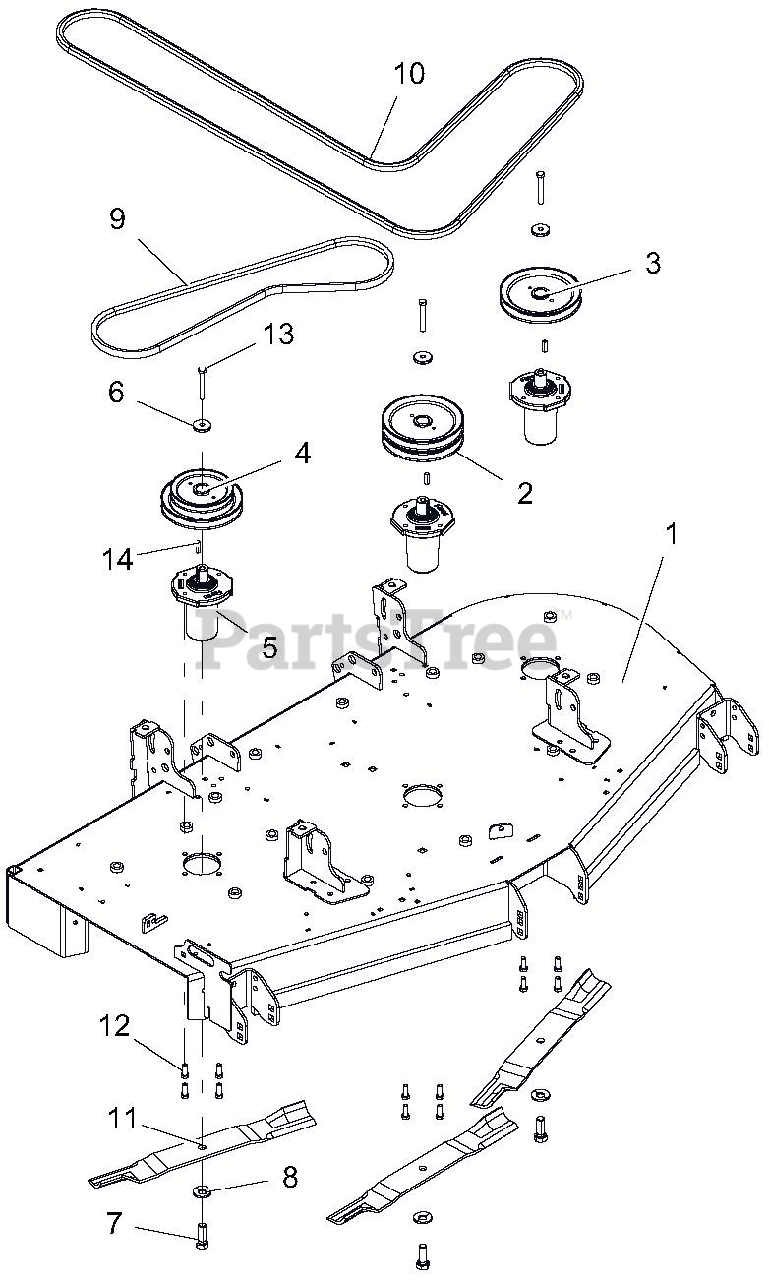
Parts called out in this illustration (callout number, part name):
1	WLDMT, 60" PT100 SIDE DISCH DECK
2	PULLEY, DOUBLE 1"ID X 6.75"OD-BLACK
3	PULLEY, V-1" ID X 6.75" OD-BLACK
4	PULLEY, DOUBLE -1" ID X 6.75" & 5.25" OD
5	SERVICE, ASM SPINDLE- DUCTILE
6	RETAINER, SHEAVE SPINDLE
7	BLT, HEX .62-18X1.75 GR8 YWZC
8	WSHR, BLVL .63X1.625X.14
9	BELT, B 63.00 RAW COGGED
10	BELT, BB 118.00 WRAPPED HEX
11	BLADE, MOWER 60"
12	BLT-HEX .38-16X1.00 GR5 YWZC EP30
13	BLT-HEX .38-16X2.75 GR8 YWZC
14	KEY-SQ .250X.250X1.00 RC 40-50
